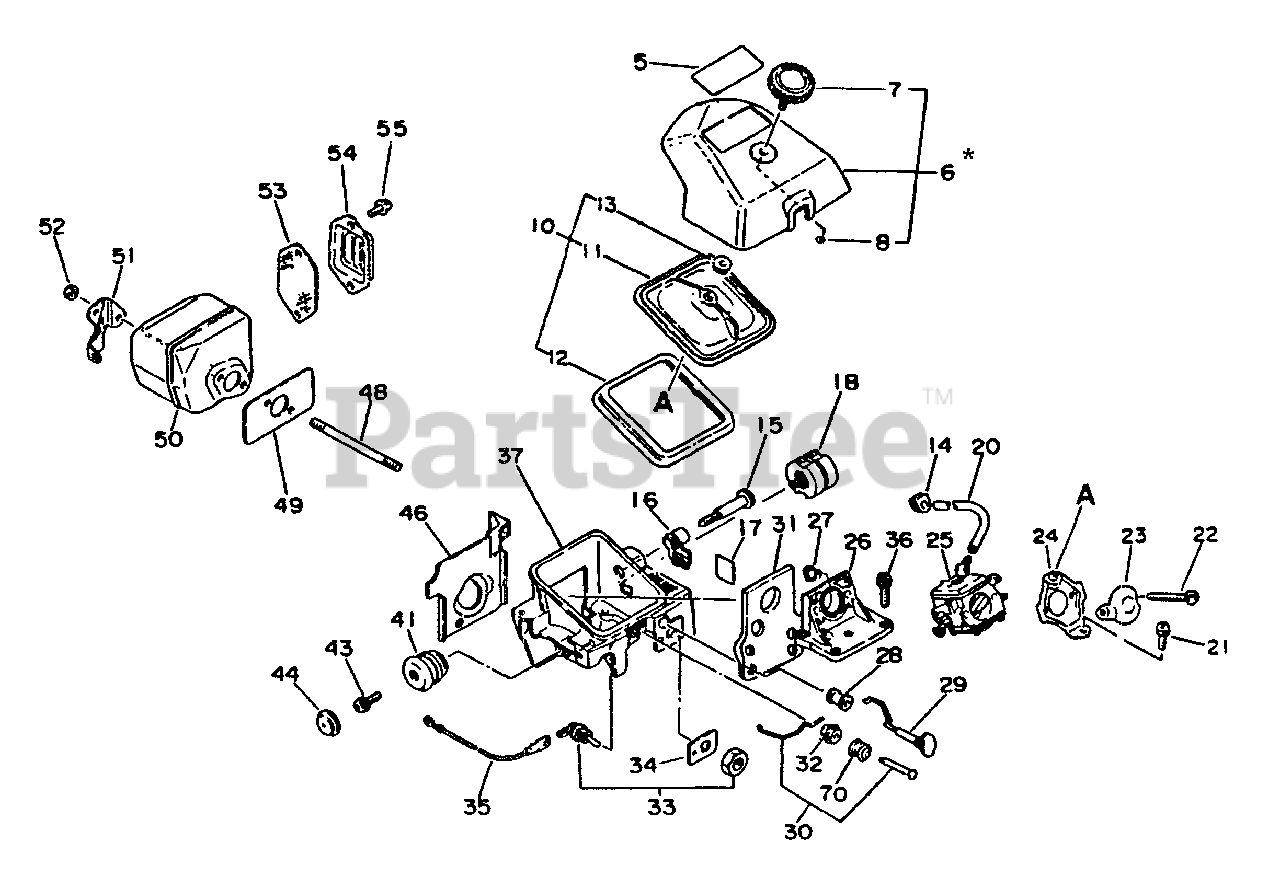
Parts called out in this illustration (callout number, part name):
5	LABEL, MODEL
6	AIR FILTER COVER ASSY
7	THUMBSCREW
8	O-RING 3
10	AIR FILTER COVER ASSY
11	FILTER, AIR
12	GASKET, CARBURETOR CASE
14	BUSHING
20	PIPE, IMPULSE
21	SCREW - 5×14
22	SCREW - 5×55
24	BRACKET, AIR FILTER
25	CARBURETOR
26	INSULATOR
27	NUT
28	GROMMET, CHOKE
29	ROD, CHOKE
30	ROD, THROTTLE
31	SEAL
32	GROMMET, THROTTLE ROD
33	SWITCH, ON-OFF
34	LABEL, STOP
35	LEAD - GROUND
36	SCREW - 5×25
37	CASE, CARBURETOR
41	CUSHION
43	SCREW - 5×10
44	CAP, CUSHION
46	PLATE, GUIDE
48	STUD
49	GASKET, EXHAUST
50	MUFFLER
52	LOCKNUT - 5
53	SCREEN, SPARK ARRESTER
54	COVER, MUFFLER
55	SCREW 4×8
